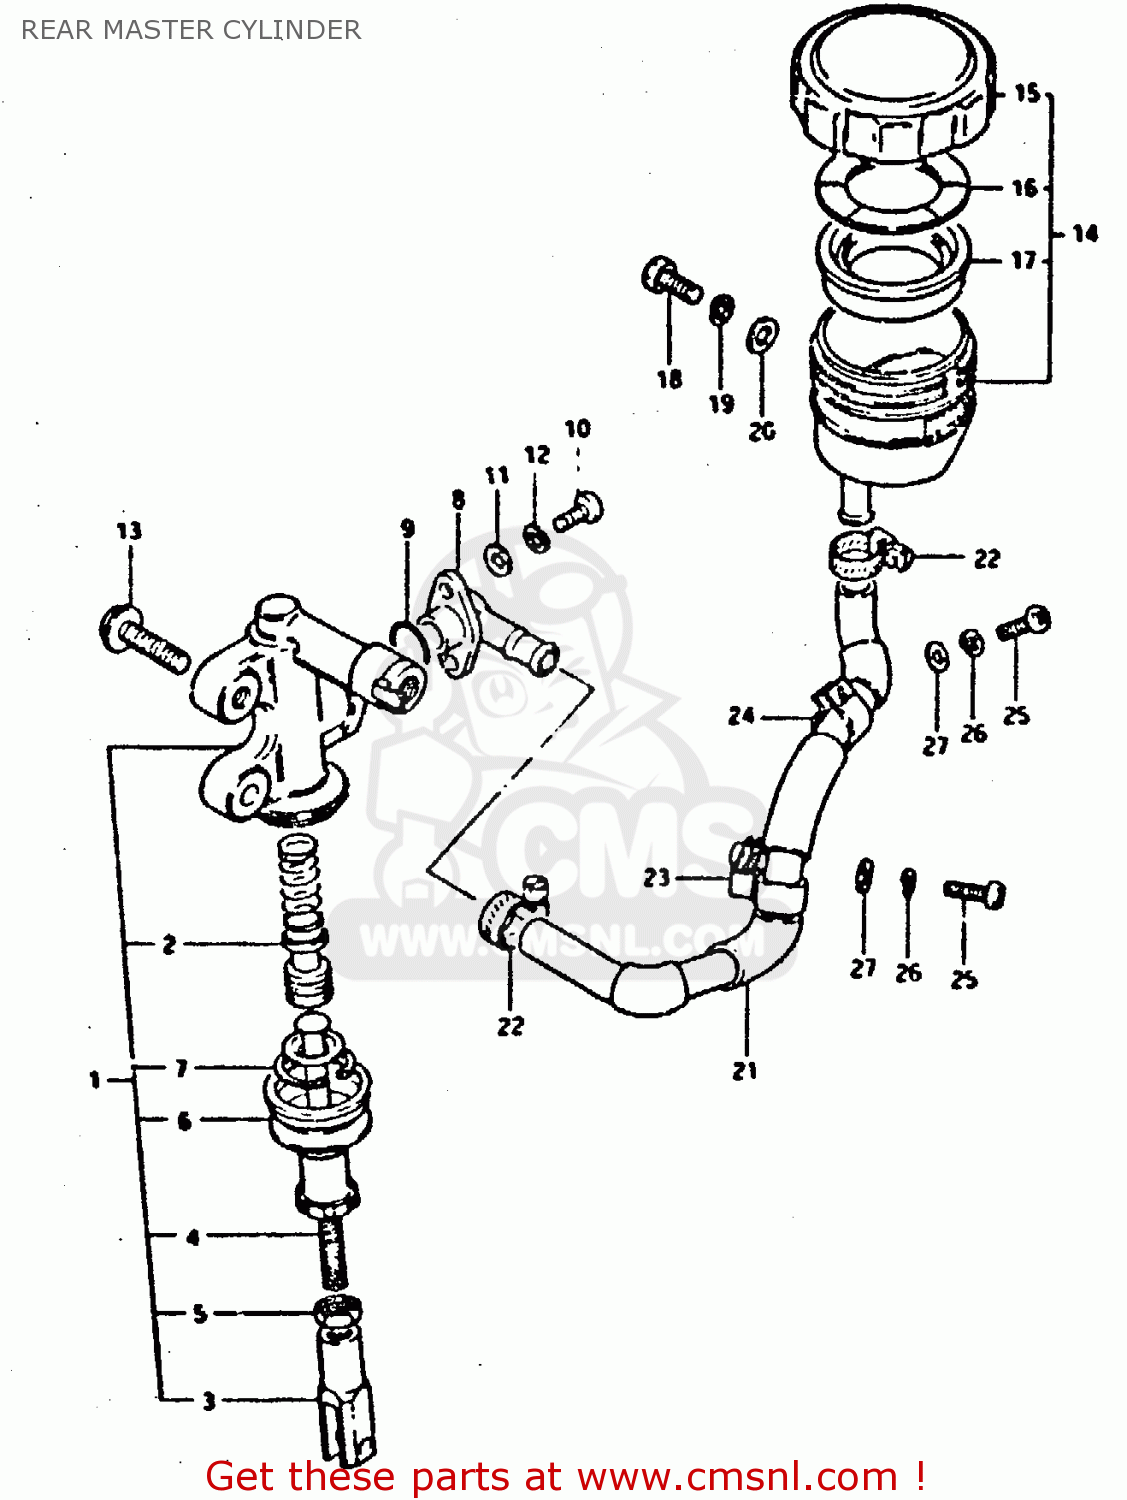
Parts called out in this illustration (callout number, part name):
1	CYLINDER ASSEMBLY,REAR MASTER
2	PISTON/CUP SET
3	YOKE
4	ROD,PUSH
5	NUT,MASTER CYLINDER
6	BOOT
7	CIRCLIP
8	CONNECTOR,HOSE
9	O RING
10	SCREW
11	WASHER
12	LOCK WASHER
13	BOLT
14	TANK ASSEMBLY,RESERVOIR
15	CAP
16	PLATE,DIAPHRAGM
17	DIAPHRAGM
18	BOLT L:16
19	LOCK WASHER
20	WASHER
21	HOSE,RESERVOIR TANK
22	CLAMP
23	CLAMP
24	CLAMP
25	SCREW 6X12
26	LOCK WASHER
27	WASHER
